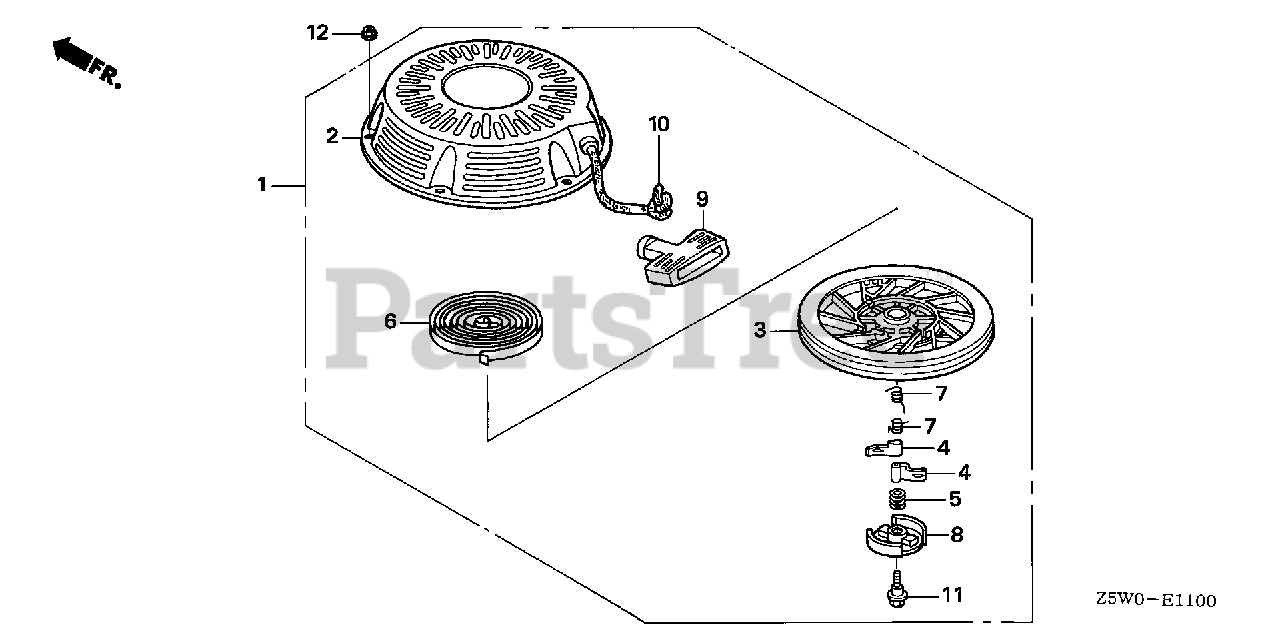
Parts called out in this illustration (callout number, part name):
1	STARTER ASSY., RECOIL *R280* (POWER RED)
2	CASE, RECOIL STARTER *R280* (POWER RED)
3	PULLEY, RECOIL STARTER
4	RATCHET, STARTER
5	SPRING, FRICTION
6	SPRING, STARTER RETURN
7	SPRING, RATCHET
8	RETAINER, SPRING
9	GRIP, STARTER
10	ROPE, RECOIL STARTER
11	SCREW, CENTER
12	NUT, FLANGE (6MM)
